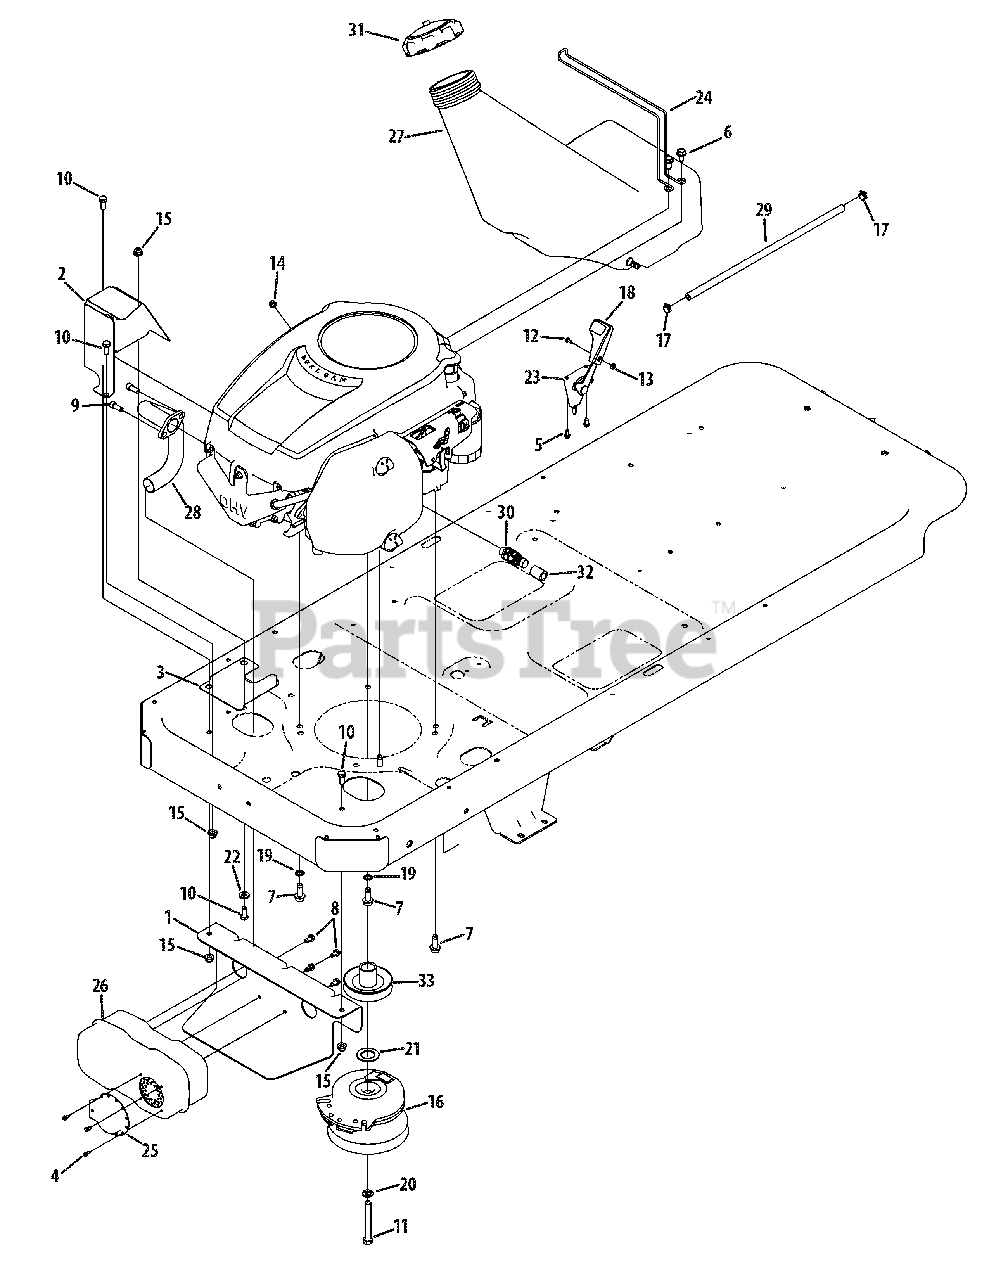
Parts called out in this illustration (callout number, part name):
1	Muffler Bracket
2	Muffler Heat Shield
3	Heat Shield
4	Hex Washer Screw, #8-18 x .500
5	Hex Washer Screw, #12-16 x .50
6	Hex Washer Screw, 5/16-18 x .750
7	Hex Washer Screw, 3/8-16 x 1.000
8	Hex Washer Screw, 1/4-20 x .500
9	Socket Head Screw, 5/16-18 x .750
10	Hex Screw, 5/16-18 x .75
11	Hex Screw, 7/16-20 x 3.25
12	Machine Screw, #8-32 x .375
13	Hex Nut, #8-32
14	Sems Nut, 1/4-20
15	Flange Lock Nut, 5/16-18
16	Electric PTO Clutch
17	Hose Clamp. .490
18	Throttle Contrl Knob
19	Lock Washer, 3/8
20	Lock Washer, 7/16
21	Flat Washer, 1.031 x 1.620 x .095
22	Flat Washer, .344 x .750 x .120
23	Throttle/Choke Control Cable
24	Tank Wire
25	Muffler Deflector
26	Single Inlet Muffler
27	Fuel Tank
28	Exhaust Pipe
29	Low Permeation Fuel Hose
30	Oil Drain
31	Fuel Cap
32	Oil Drain Extension Hose
33	Electric PTO Engine Pulley
